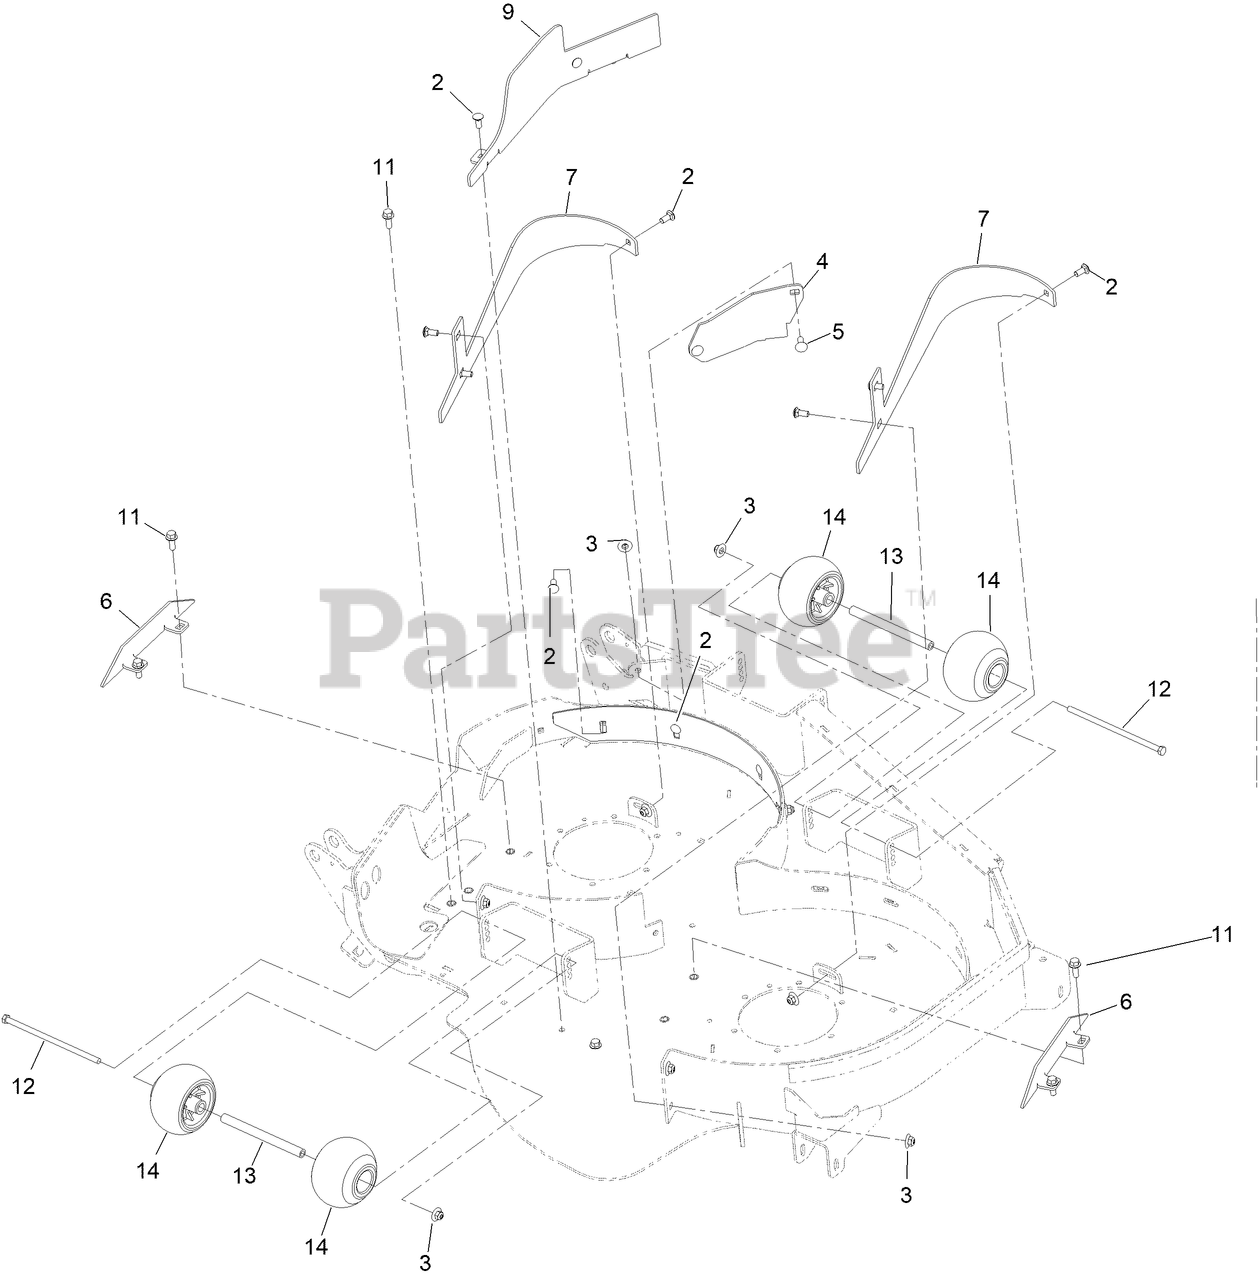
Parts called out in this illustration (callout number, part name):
2	BOLT-CARR
3	NUT-FLANGE, NI
4	PLATE-FILL, LH DECK
5	BOLT-CARR
6	PLATE-BAFFLE STRAIGHT RH
7	BAFFLE-DOGLEG, OUTSIDE
9	BAFFLE-CENTER, LH
11	SCREW-HHF
12	SCREW-HH
13	SPACER-WHEEL
14	ROLLER-SCALP, ANTI
